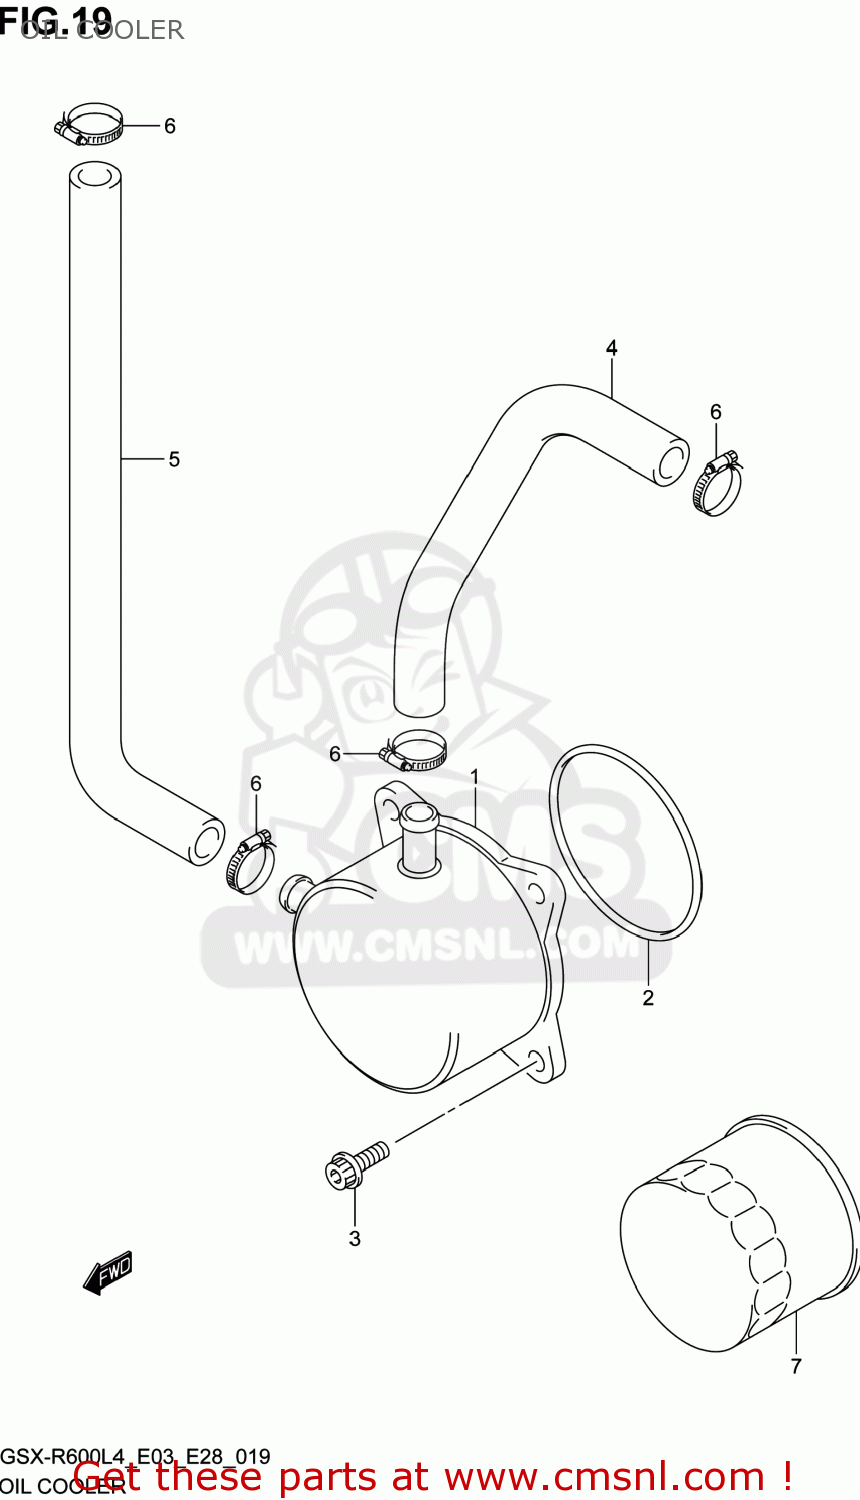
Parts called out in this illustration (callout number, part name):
1	COOLER ASSY,OIL
2	O RING(D:3.1,ID:63.9)
3	BOLT(6X16)
4	HOSE,OIL COOLER WATER INLET
5	HOSE,OIL COOLER WATER OUTLET
6	CLAMP
7	FILTER ASSY,ENGINE OIL
